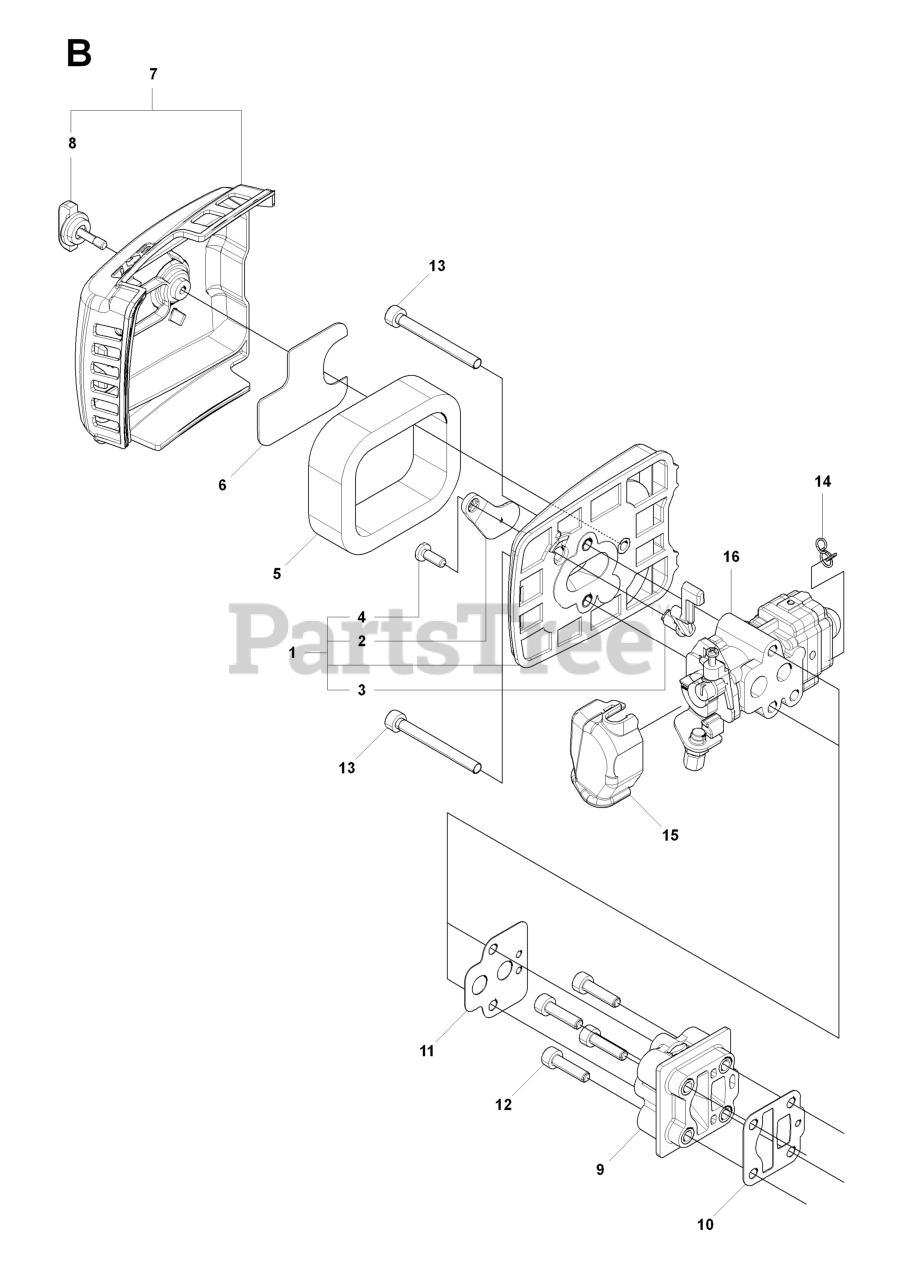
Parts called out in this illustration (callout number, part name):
2	PLATE, choke
4	SCREW
7	COVER ASSY
8	KNOB
9	%INSULATOR
10	GASKET, INSU
11	GASKET, CARB
13	BOLT TORX M5XL50 T27
14	CLIP
15	COVER
16	CARBURETOR ASSY
